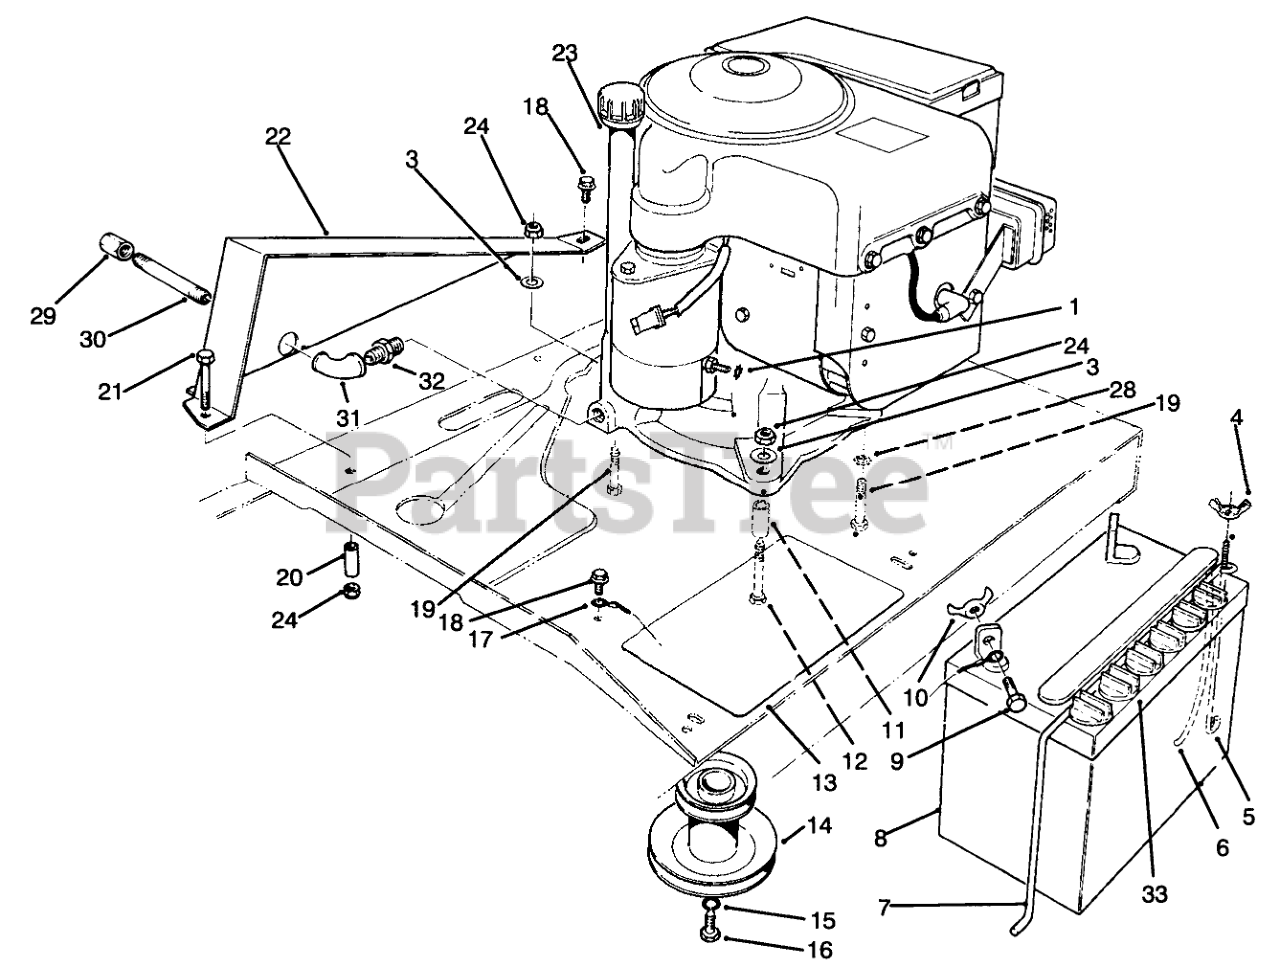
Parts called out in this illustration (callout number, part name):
1	WASHER-LOCK/EXT
3	WASHER-PLAIN
4	NUT-WING SPECL
5	POST-BATTERY
6	TUBE-BATT DRAIN/80-2600
7	HOLDDOWN-BATTERY
8	Battery
9	SCREW-HH
10	NUT-WING
11	SPACER-PIVOT
12	SCREW-HH
13	PAD-SKID, ANTI
14	Pulley-Engine
15	WASHER-FLAT
16	SCREW-HH
17	WIRE ASM(BATT/GRD.
18	SCREW-HWHTF
19	SCREW-HH
20	GUIDE-BELT
21	SCREW-HH
22	GUIDE-CHAIN
23	Engine-8 H.P. B & S
24	NUT-LOCK, NI
28	WASHER-LOCK
29	CAP-PIPE
30	NIPPLE-PIPE
31	ELBOW-STREET
32	BUSHING-PIPE
33	BATTERY CAP
